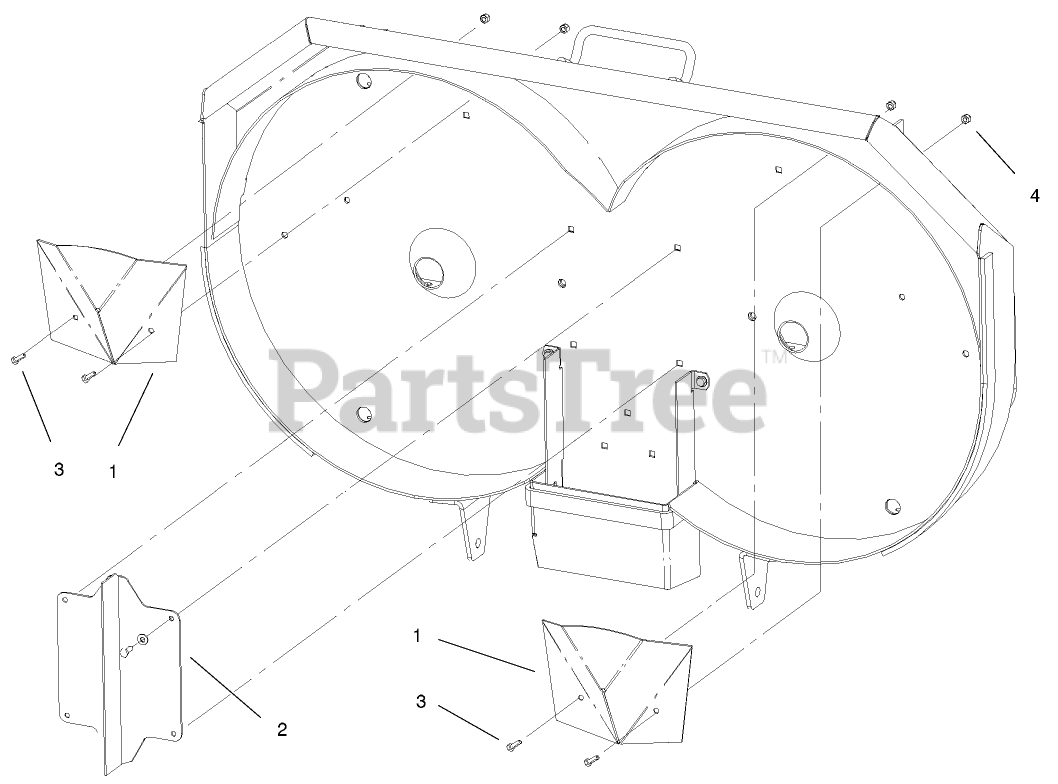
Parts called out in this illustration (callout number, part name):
1	Kicker-Baffle
2	Divider Baffle ASM
3	SCREW-HH
4	NUT-LOCK, NI
